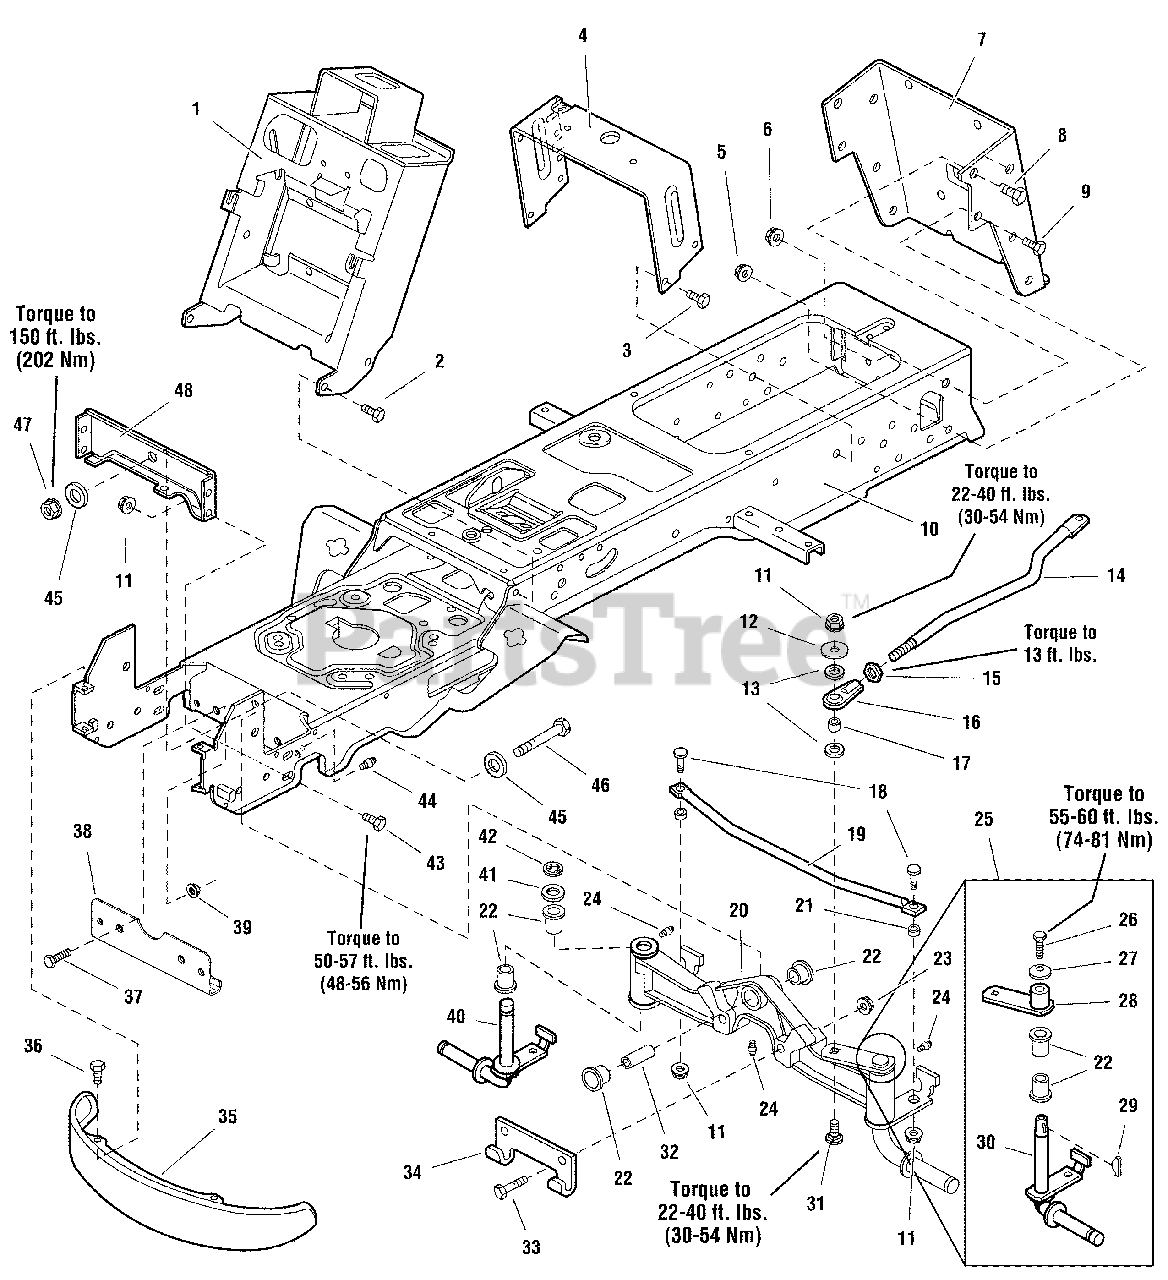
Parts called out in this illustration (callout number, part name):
1	TOWER & SUPPORT ASSEMBLY
2	CAPSCREW, Hex Washer Head Taptite, 3/8-16 x 3/4
3	CAPSCREW, Hex Head, Taptite, 5/16 -18 x 3/4
4	SUPPORT, Seat Deck
5	NUT, Hex Flange 3/8-16 Whiz Lock, Large
6	NUT, Hex Flange, Two-Way Lock, 1/2-13
7	BACKPLATE
8	CAPSCREW, Hex Head 1/2-13 x 1, Black
9	CAPSCREW, Hex Head 3/8-16 x 1, Black
10	FRAME ASSEMBLY, Front & Rear
11	NUT, Hex Flange Two-Way Lock, 3/8-16
12	WASHER, 3/8, Black
13	WASHER, 3/8, Black
14	LINK, Drag
15	NUT, Hex Jam 1/2-20
16	JOINT, Ball
17	SPACER, 3/8 x 1/2 x 5/8
18	CARRIAGE BOLT, 3/8-16 x 1
20	AXLE ASSEMBLY w/LH Spindle
21	SPACER, 25/64 x 5/8 x 5/16, Powder Metal
22	BUSHING, 31/32 x 1-1/4 x 3/4, Powder Metal
23	NUT, Hex Flange Two-Way Lock, 7/16-14
24	FITTING, Lube
25	SPINDLE REPLACEMENT KIT, LH
26	CAPSCREW, 3/8-16 x 7/8, GR8
27	WASHER, Spring, 3/8
28	HUB & ARM ASSEMBLY
29	KEY, Woodruff
30	SPINDLE, LH
31	BOLT, Carriage, Short Neck, 3/8-16 x 1-1/2
32	SPACER, 11/16 x 21/32 x 2 3/32
33	CAPSCREW, Hex Head, 7/16-14 x 2, G8, Black
34	HOOK, Hitch, 5/16
35	BUMPER, Black
36	SCREW, Truss Head Torque Drive, 5/16-18 x 7/8
37	CAPSCREW, Hex Whiz Lock, 5/16-18 x 3/4
38	PLATE, Axle Wear
39	NUT, Hex Flange Whiz Lock, 5/16-18
40	SPINDLE, RH
41	WASHER
42	RING, Retainer
43	CAPSCREW, Hex Flange Whiz Lock, 3/8-16 x 3/4
44	FITTING, Grease for Wear Plate
45	WASHER, 5/8
46	CAPSCREW, Hex Head, 5/8-11 x 3-1/2
47	NUT, Hex Flange Two-Way Lock, 5/8-11
48	PLATE, Axle
